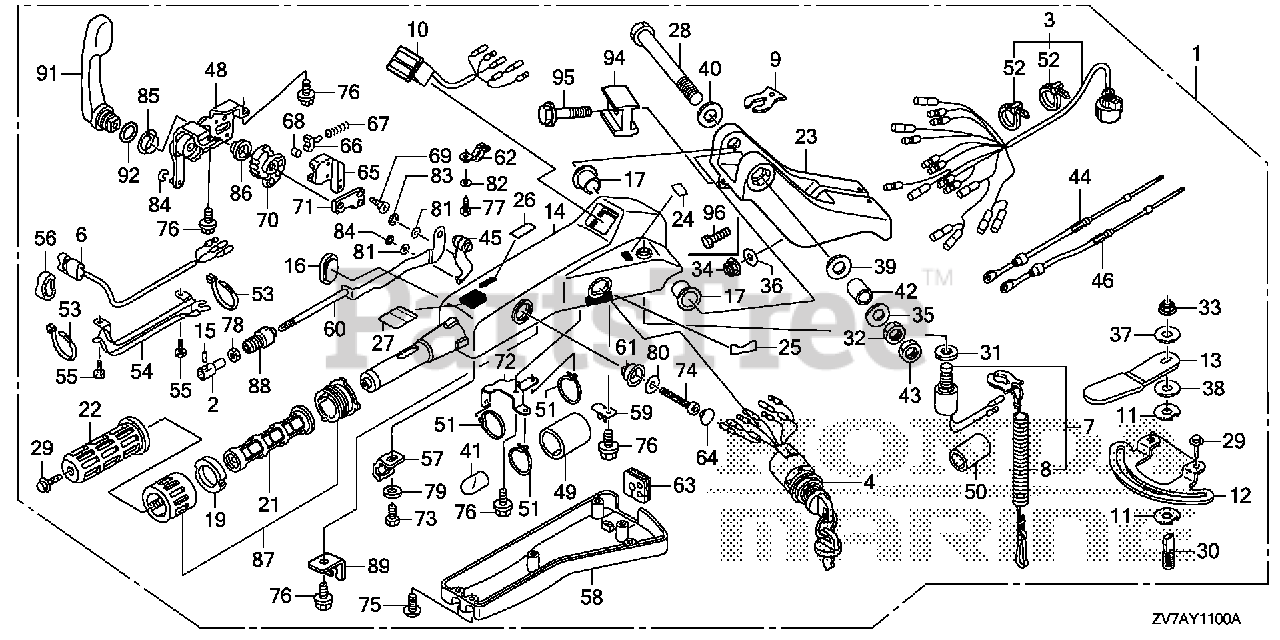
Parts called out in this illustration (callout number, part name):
1	HANDLEBAR KIT *NHB14M* (AQUA MARINE SILVER METALLIC)
2	PIVOT, THROTTLE CABLE
3	CABLE ASSY., LONG HANDLE (A)
4	SWITCH ASSY., COMBINATION
7	SWITCH ASSY., EMERGENCY STOP
8	WIRE, EMERGENCY
9	CLIP, EMERGENCY LOCK
10	LAMP ASSY., INDICATION (2-LED)
11	BLOCK, FRICTION
12	PLATE, FRICTION
13	LEVER, FRICTION
14	HOUSING *NHB14M* (AQUA MARINE SILVER METALLIC)
15	PIN, THROTTLE CABLE
16	GROMMET, POWER TILT SWITCH
17	BUSH, HANDLEBAR
19	PAD, THROTTLE FRICTION
21	PIPE, GRIP
22	RUBBER, GRIP
23	BRACKET, STEERING *NHB14M* (AQUA MARINE SILVER METALLIC)
24	MARK, EMERGENCY SWITCH INDICATION (EU)
25	MARK, STARTER (ENGLISH)
26	MARK, CHANGE
27	MARK, THROTTLE (ENGLISH)
28	BOLT, HEX. (12X80)
29	BOLT, FLANGE (6X12)
30	BOLT, STUD (8X26)
31	NUT, HEX. (16MM)
32	NUT, HEX. (12MM)
33	NUT, SELF-LOCK (8MM)
34	NUT, SELF-LOCK (10MM)
35	WASHER, WAVE (14MM)
36	WASHER (10MM)
37	WASHER (8MM)
38	WASHER, NYLON (8MM)
39	WASHER, PLAIN (12MM)
40	WASHER, PLAIN (12MM)
41	TUBE, CORD (30MM)
42	COLLAR, DISTANCE (12.2X23X16)
43	NUT, HEX. (12MM)
44	CABLE, THROTTLE
45	ARM, THROTTLE
46	CABLE, SHIFT
48	FRAME ASSY., SHIFT
49	TUBE (38.1X40)
50	TUBE (19X40)
51	BAND (CONVEX CV-150)
52	BAND (CONVEX CV-200)
57	HOLDER, SWITCH
58	COVER, HANDLEBAR (LOWER)
59	BRACKET, CABLE
60	PLATE ASSY., LOCK
61	STOPPER
62	PLATE, GUIDE
63	GROMMET
64	CAP
65	GUIDE, SPRING
66	ACTUATOR
67	SPRING, COIL
68	ROLLER
69	SCREW (M5X14)
70	GEAR, SHIFT
71	PLATE, BALL GUIDE
72	BRACKET
73	BOLT (M5X8)
74	BOLT (M8X50)
75	BOLT (M5X12)
76	BOLT (M6X12)
77	BOLT (M5X12)
78	NUT, HEX. (5MM)
79	WASHER (5MM)
80	WASHER (8MM)
81	WASHER (10MM)
82	WASHER (5MM)
83	E-RING
84	E-RING
85	BEARING
86	BEARING
87	GRIP ASSY., THROTTLE FRICTION
88	ROD, GROMMET
89	CLAMP, BRACKET
91	LEVER, SHIFT
92	O-RING (20.6X1.9)
94	BLOCK, HEIGHT ADJUSTER
95	BOLT, FLANGE (8X28)
96	BOLT, HEX. (10X32)
